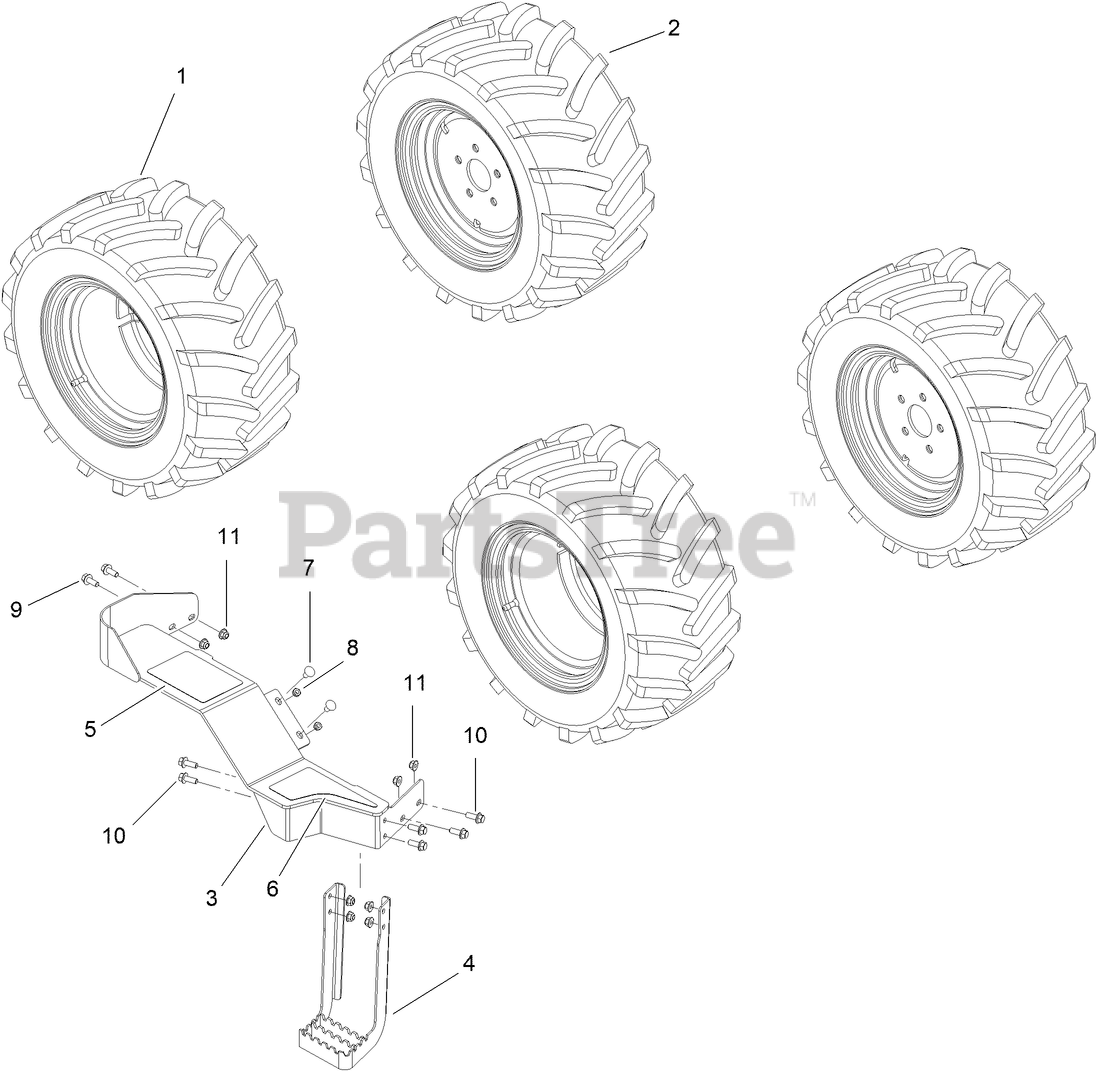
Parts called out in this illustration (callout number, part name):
1	TIRE/WHEEL 23X10.50-12
2	TIRE/WHEEL 23X10.50-12
3	PLATFORM-EXTENSION
4	STEP-PLATFORM
5	NON-SKID
6	NON-SKID
7	SCREW-CARR
8	NUT-HEX
9	SCREW-HHF
10	SCREW-HHF
11	NUT-HF, NI
